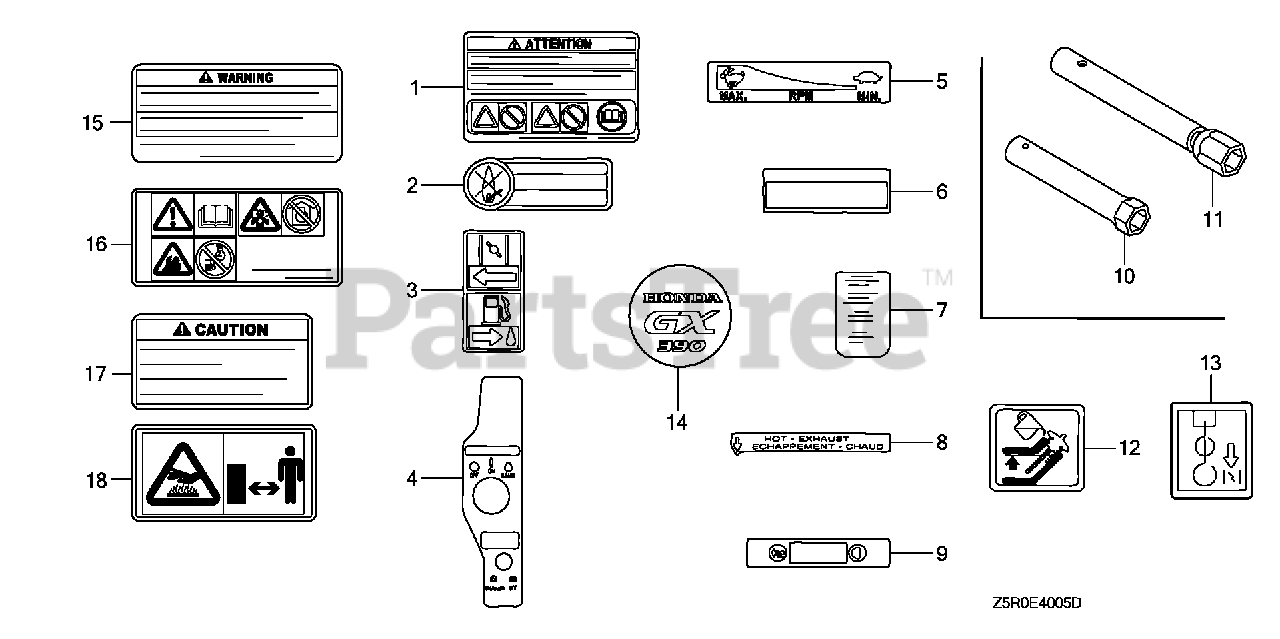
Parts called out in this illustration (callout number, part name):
1	MARK, OPERATOR CAUTION (FRENCH)(MADE IN JAPAN)
1	MARK, OPERATOR CAUTION (ENGLISH)(MADE IN JAPAN)
15	MARK, OPERATOR CAUTION (FRENCH)(MADE IN JAPAN)
15	MARK, OPERATOR CAUTION (ENGLISH)(MADE IN JAPAN)
16	MARK, OPERATOR CAUTION (PICTOGRAPH)
17	MARK, EX. CAUTION (ENGLISH)
17	MARK, EX. CAUTION (FRENCH)
